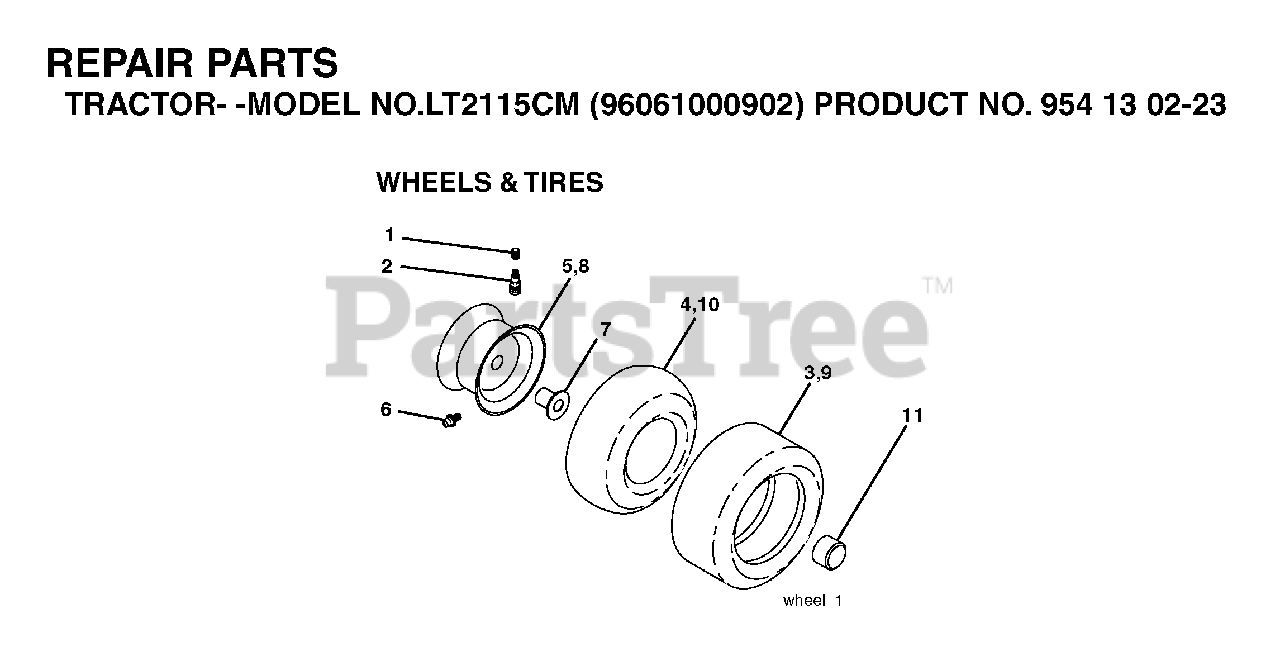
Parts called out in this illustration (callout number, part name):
1	VALVE CAP
2	VALVE STEM LT
3	TIRE HEAVY DUTY
4	TUBE.5.3/4.5/6
5	RIM ASM 6" FRONT SILVER
6	FITTING LT
7	BEARING T
8	RIM ASM 8" REAR SILVER
9	TIRE HEAVY DUTY
10	TUBE
11	CAP, AXLE BLK
